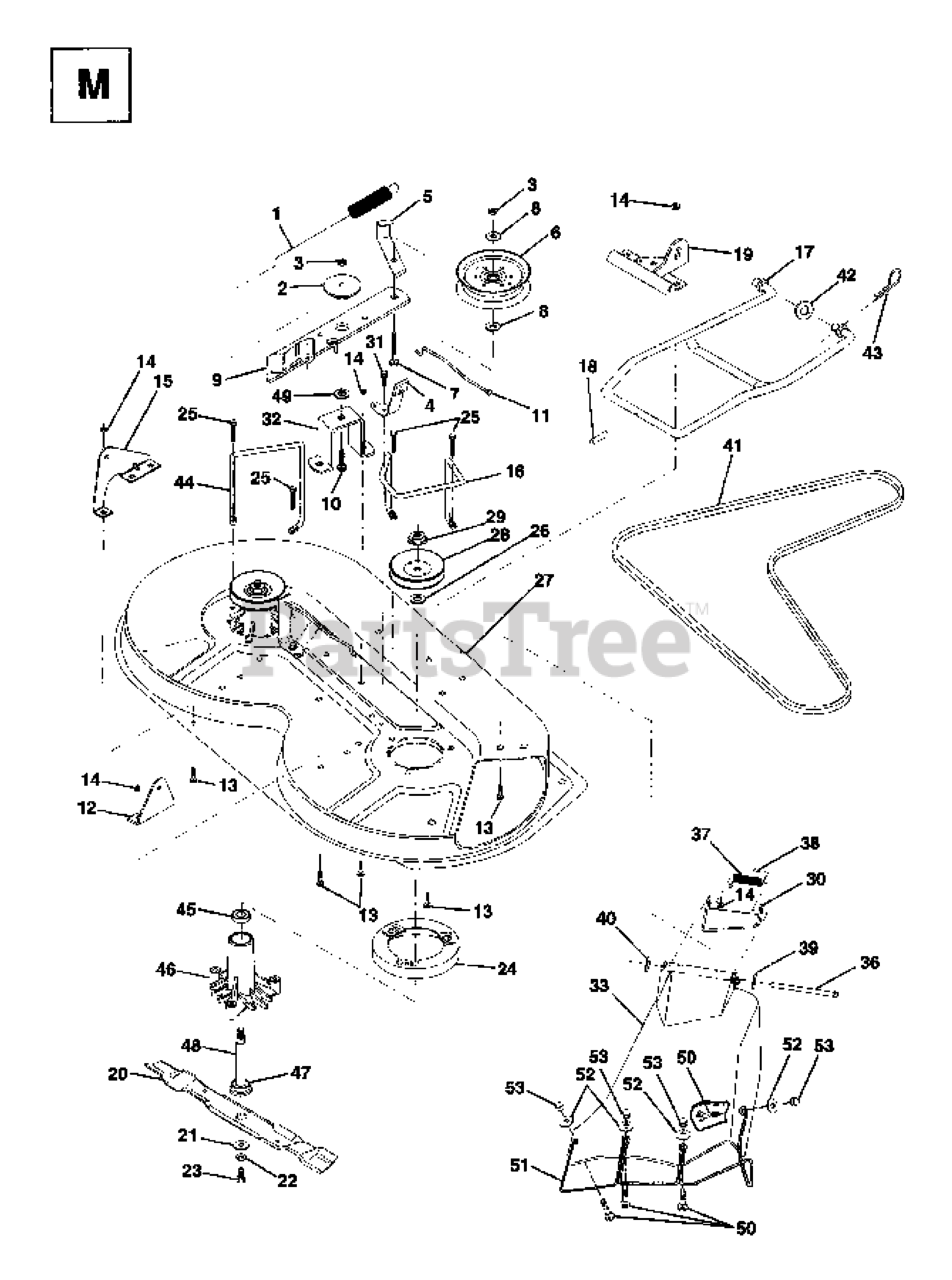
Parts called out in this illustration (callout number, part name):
1	SPRING-MOWER CLUTCH
2	SPACER RETAINER
4	BRAKE ASSEMBLY
5	IDLER BELT GUIDE
6	PULLEY.IDLER.FLAT.MOWER.BLK.PT
8	WASHER
9	IDLER ARM ASSY
10	BOLT.3/8-14X1.25
12	BRKT LIFT REAR
13	RP BOLT 5/16-18 X3/4 ZN/YEL GR
14	LOCKNUT
15	BRKT LIFT REAR LH
16	KEEPER RH
17	MOWER LINK STABILIZER
18	PIN GROOVE
19	BRKT LINK STABILIIZER
20	BLADE, HI-LIFT 36" PREMIUM
21	WASHER.BLADE
22	LOCKWASHER
23	BLADE BOLT
24	STRIPPER
25	SCREW
26	WASHER
27	MOWER HOUSING
28	PULLEY
29	NUT
30	BRACKET ASM DEFLECTOR
31	Screw 5/16-18 x 1/2 Hex, Self Tapping 5/16-18 x 1/2
32	SUPT,IDLER ARM
33	DEFLECTOR
36	HINGE ROD
37	SPRING TORSION
38	CAP-SLEEVE LT
39	Washer 11/32 x 5/8 x 16 Ga SD
40	NUT PUSH M
42	WASHER
43	SPRING RETAINER
46	HOUSING.MANDREL.VENTED (MACHD)
47	BEARING.BALL.#6204.(MANDREL)
48	SHAFT ASM VENT
49	HARDENED WASHER
52	WASHER
